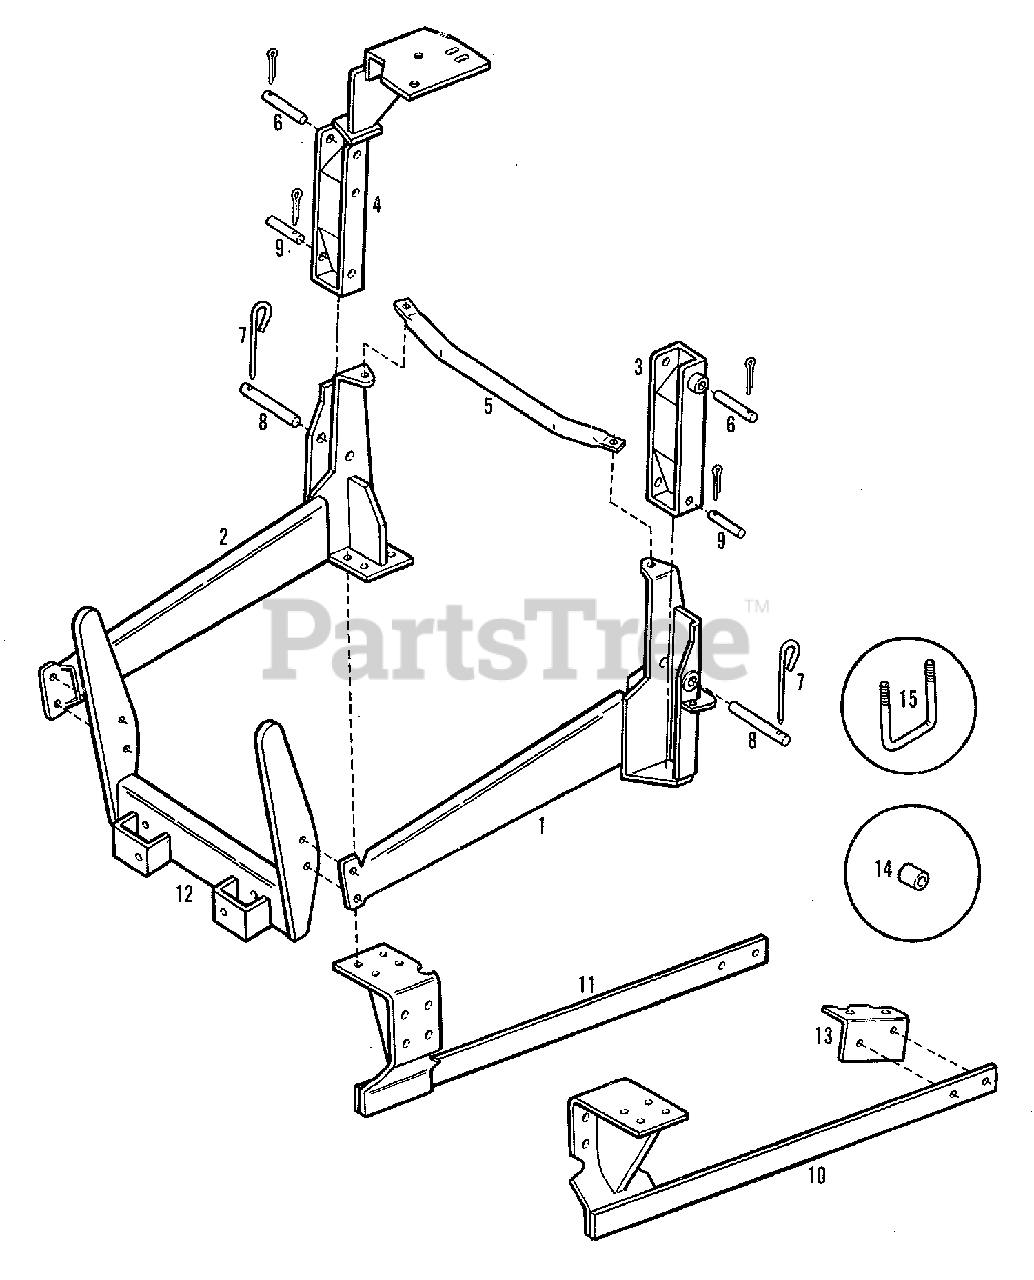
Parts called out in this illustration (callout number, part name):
1	FRAME ASSEMBLY, L.H.
1	CAPSCREW, 1/2NC x 1-1/2
1	WASHER, Plain, 17/32 x 1-1/4 x 14 GA
1	LOCKWASHER, 1/2
2	FRAME ASSEMBLY, R.H.
2	CAPSCREW, 1/2NC x 1-1/2
2	WASHER, Plain 17/32 x 1 x 14 Ga.
2	LOCKWASHER, 1/2
3	SUPPORT ASSEMBLY, L.H.
4	SUPPORT ASSEMBLY, R.H.
5	BRACE, Cross
5	CAPSCREW, 1/2NC x 1-1/2
5	LOCKWASHER, 1/2
6	PIN, Boom Pivot
6	PIN, Cotter, 1/4 x 2
7	PIN, Locking, Support Assembly
8	PIN, Attaching, Support Assembly
9	PIN, Cotter, 1/4 x 2
9	PIN, Cylinder, Rear
10	PAD ASSEMBLY, Mounting, L.H. (Prior to S/N 1199)
10	PAD ASSEMBLY, Mounting, L.H. (Eff. S/N 1199 & Up)
10	CAPSCREW, 12MM x 1-1/2 x 35MM
10	CAPSCREW, 1/2NC x 2
10	WASHER, Plain, 17/32 x 1 x 14 GA
10	LOCKWASHER, 1/2
11	PAD ASSEMBLY, Mounting, R.H. (Prior to S/N 1199)
11	PAD ASSEMBLY, Mounting, R.H. (Eff. S/N 1199 & Up)
11	CAPSCREW, 12MM x 1-1/2 x 35MM
11	CAPSCREW, 1/2NC x 2
11	WASHER, Plain, 17/32 x 1 x 14 GA
11	LOCKWASHER, 1/2
12	SUPPORT ASSEMBLY, Front
12	CAPSCREW, 1/2NC x 3
12	LOCKWASHER, 1/2
13	BRACKET, Rear Mounting, L.H. (Prior to S/N 1199)
13	BRACKET, Rear Mounting, L.H. (Eff. S/N 1199 & Up)
13	BRACKET, Rear Mounting, R.H. (Prior to S/N 1199)
13	BRACKET, Rear Mounting, R.H. (Eff. S/N 1199 & Up)
13	CAPSCREW, 1/2NC x 6
13	LOCKWASHER, 1/2
14	SPACER, Rear Mounting Bracket
15	U-BOLT, Rear Mounting Bracket
15	LOCKWASHER, 1/2
